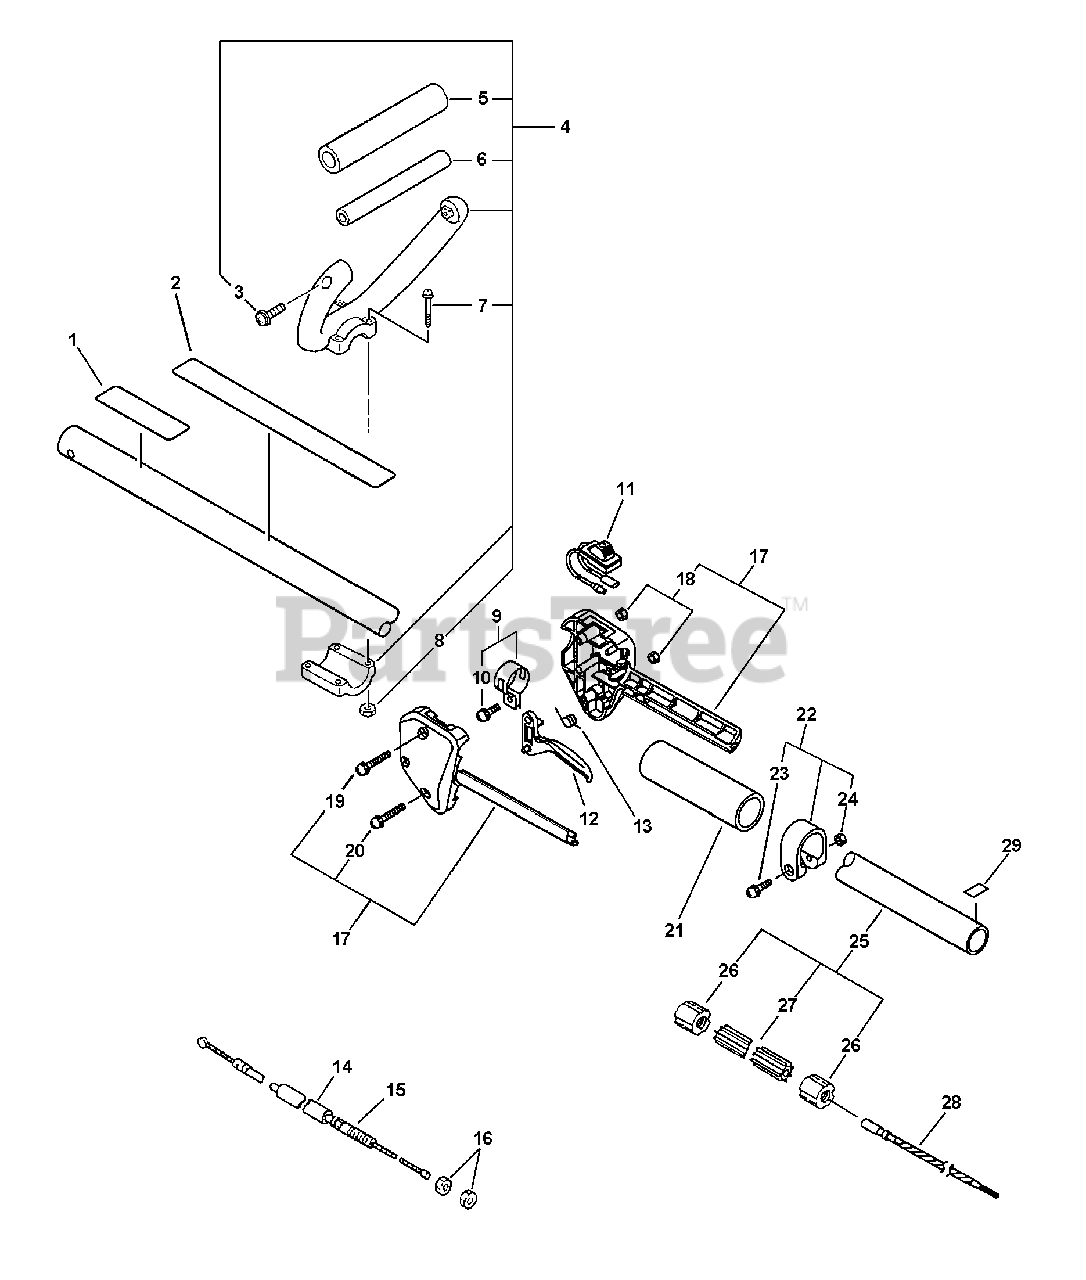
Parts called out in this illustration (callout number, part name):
1	LABEL - CAUTION
2	LABEL - CAUTION
3	SCREW 5×30
4	LOOP HANDLE ASSY
5	GRIP, HANDLE
7	SCREW 5×35
8	NUT M5
9	CLAMP KIT
10	SCREW 5×14
11	IGNITION SWITCH ASSY
12	TRIGGER, THROTTLE
13	SPRING, TORSION
15	CABLE, THROTTLE
17	HANDLE KIT, CONTROL
18	NUT M5
19	SCREW 5×35
20	SCREW 5×25
21	GRIP, HANDLE
22	CLAMP KIT
23	SCREW 5×30
24	NUT M5
25	MAIN PIPE ASSY 25×1500
27	LINER - FLEXIBLE
28	DRIVESHAFT - FLEXIBLE L= 1522
29	LABEL - ALIGNMENT
